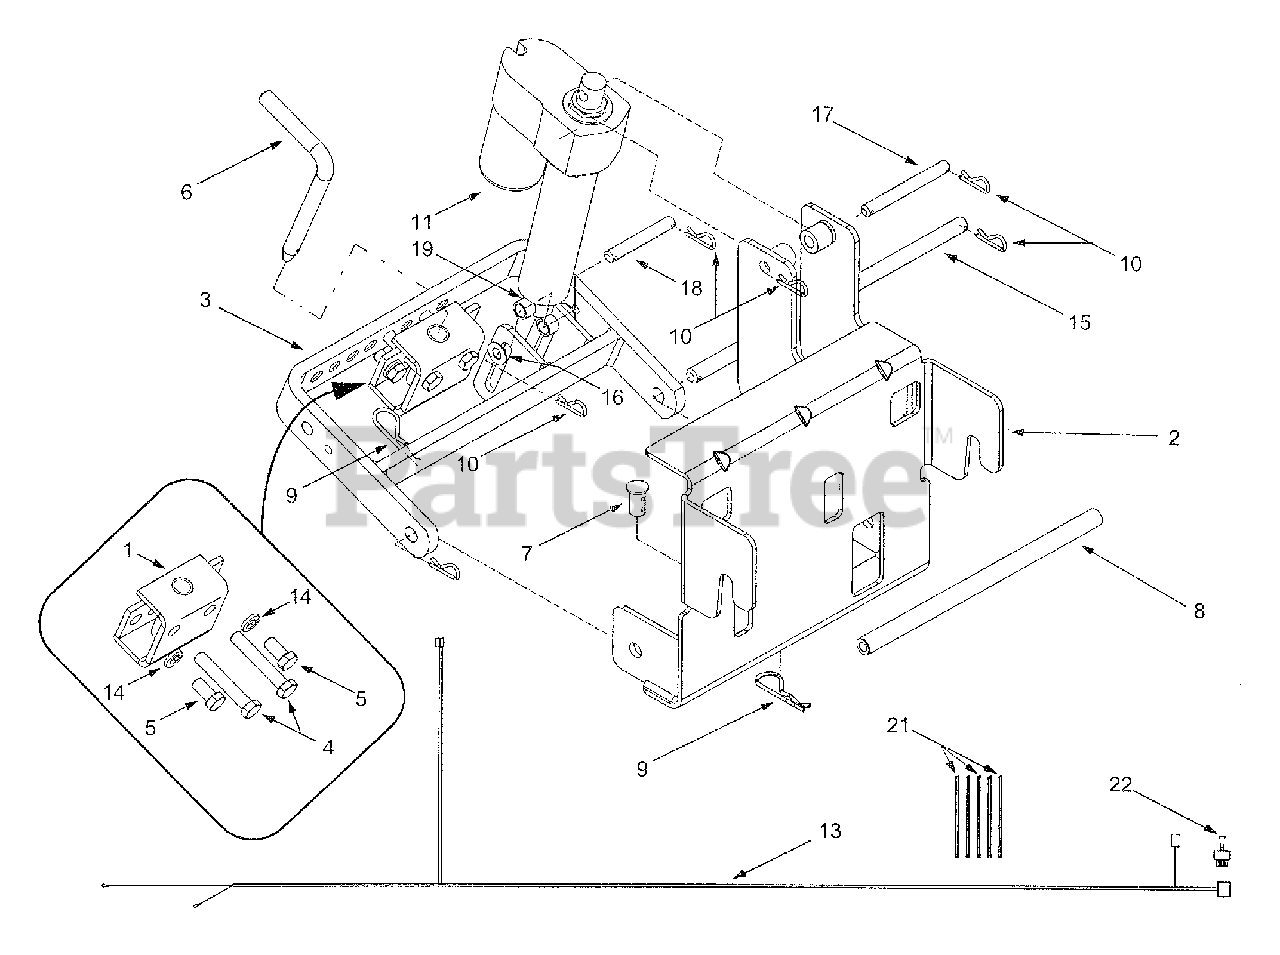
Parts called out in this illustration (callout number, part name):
5	Hex Cap Screw, 1/2-13 x 1 (Grade 5)
6	Hitch Pin
7	Clevis Pin
8	Support: Rod, 3/4 x 13"
9	Internal Cotter Pin, .148 x 3
10	Internal Cotter Pin
11	Electromechanical Linear Actuator
13	Wire Harness
14	Lock Washer, 1/2
15	Hitch Rod
16	Flat Washer, .51 x 1.12 x .060
17	Upper Cylinder Support Rod
18	Lower Cylinder Support Rod
19	Spacer, .542 x .750 x .5
22	Toggle Switch
